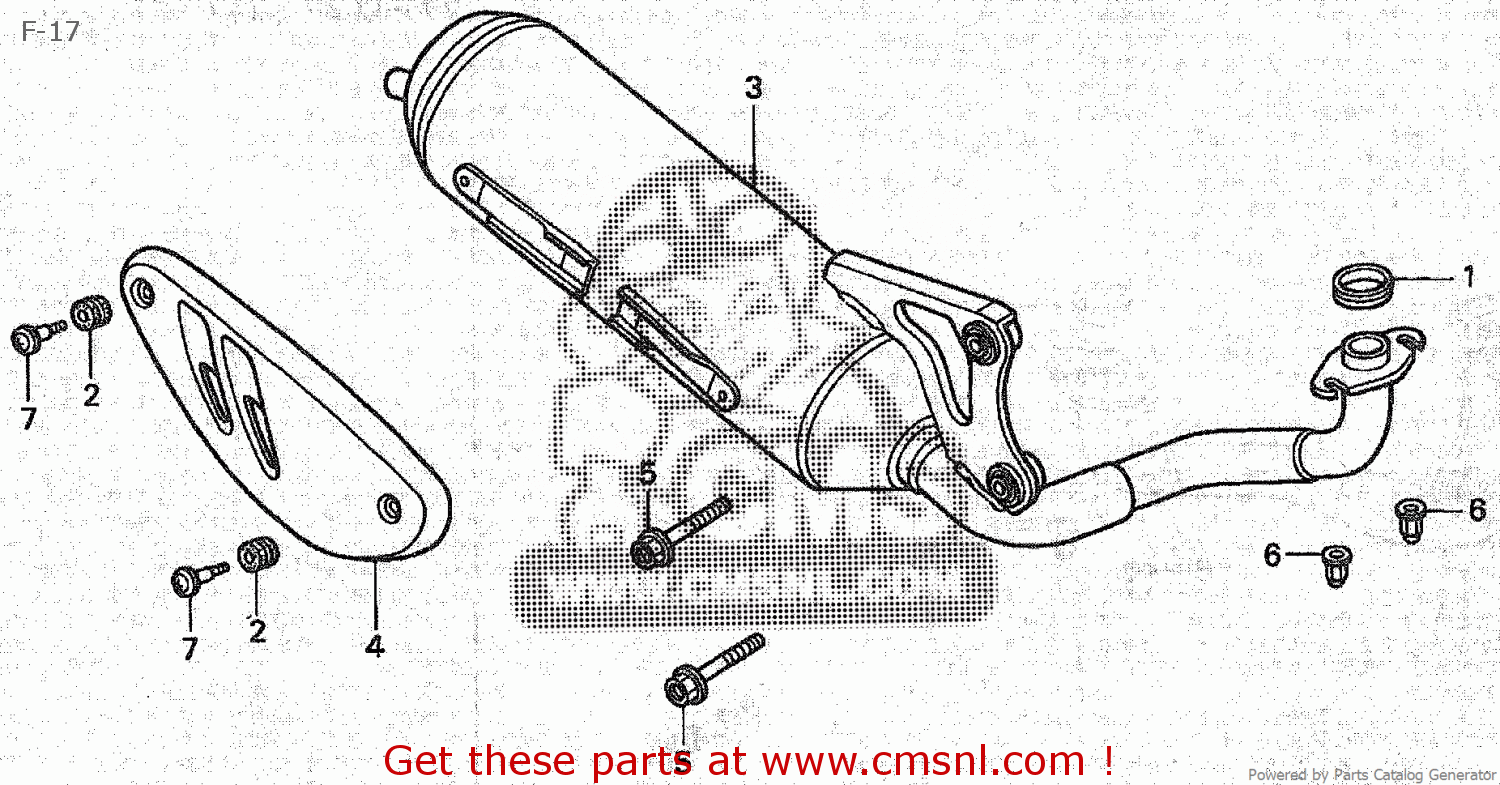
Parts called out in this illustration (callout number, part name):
1	GASKET,EXH.PIPE (NAS)
2	RUBBER,PACKING PR (NAS)
3	MUFFLER COMP,EXH.
4	PROTECTOR,MUFF.
5	BOLT,FALNGE 8X35
6	NUT,6MM CAP WASHE
7	SCREW,PAN,5X12.5
